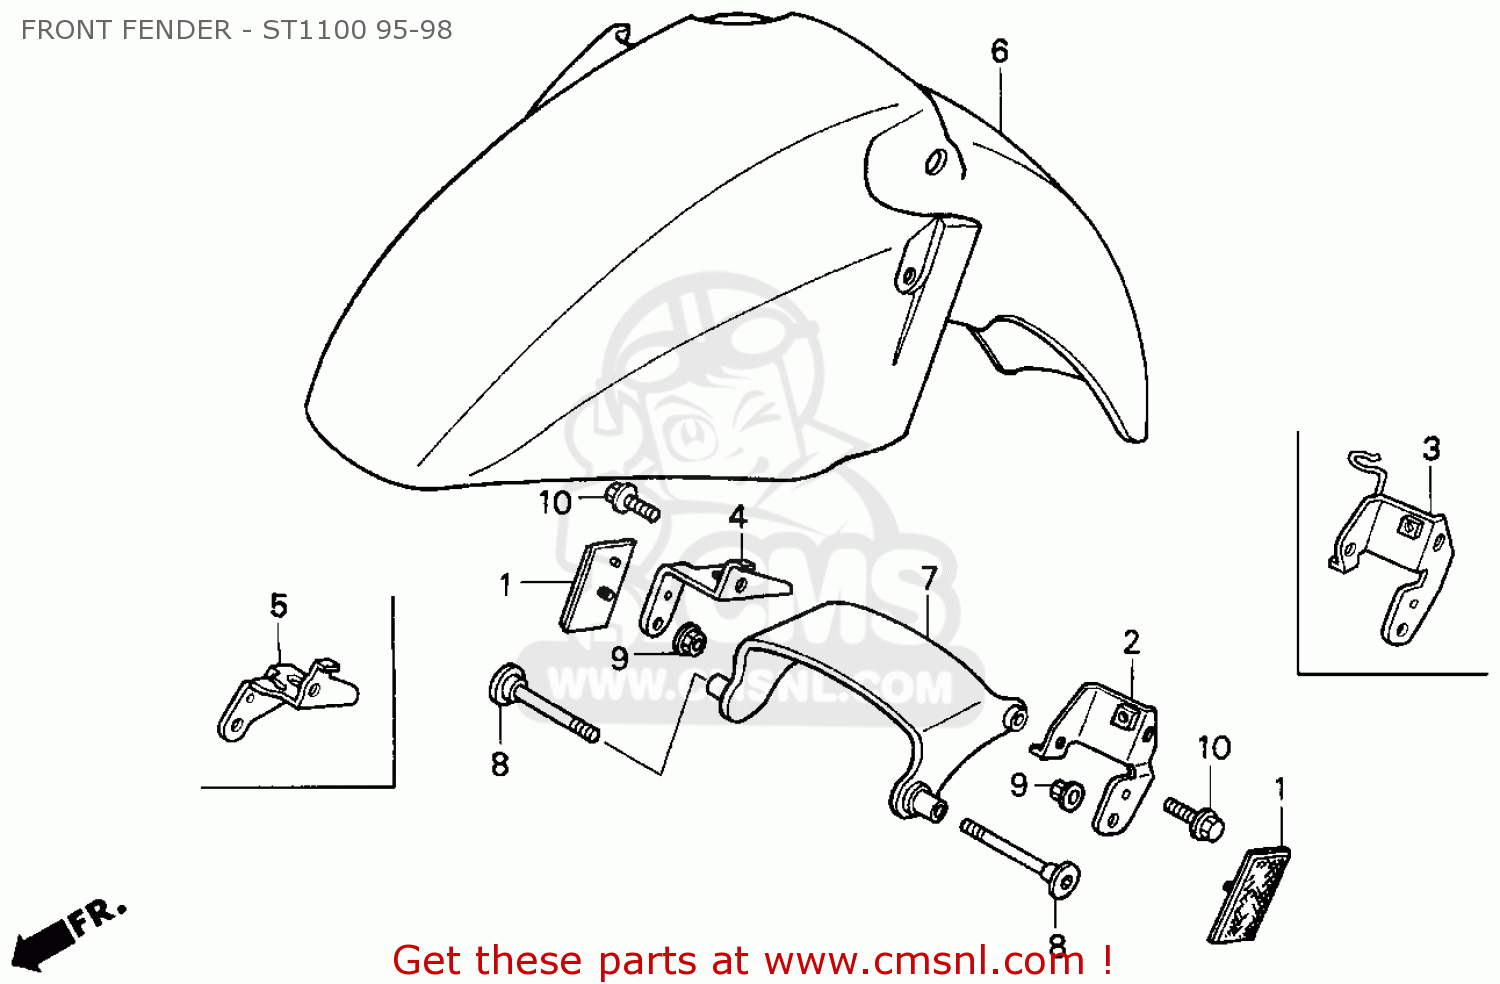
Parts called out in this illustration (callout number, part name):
1	REFLECTOR,FR,RFLX
2	STAY,L.FR.BRAKE H
4	STAY,R.FR.BRAKE H
6	FRONT FEND*R158P*
7	PLATE L,FR.FENDER
8	SCREW,PAN 6X46
9	NUT,FLANGE,5MM
10	BOLT,FLANGE,6X22
